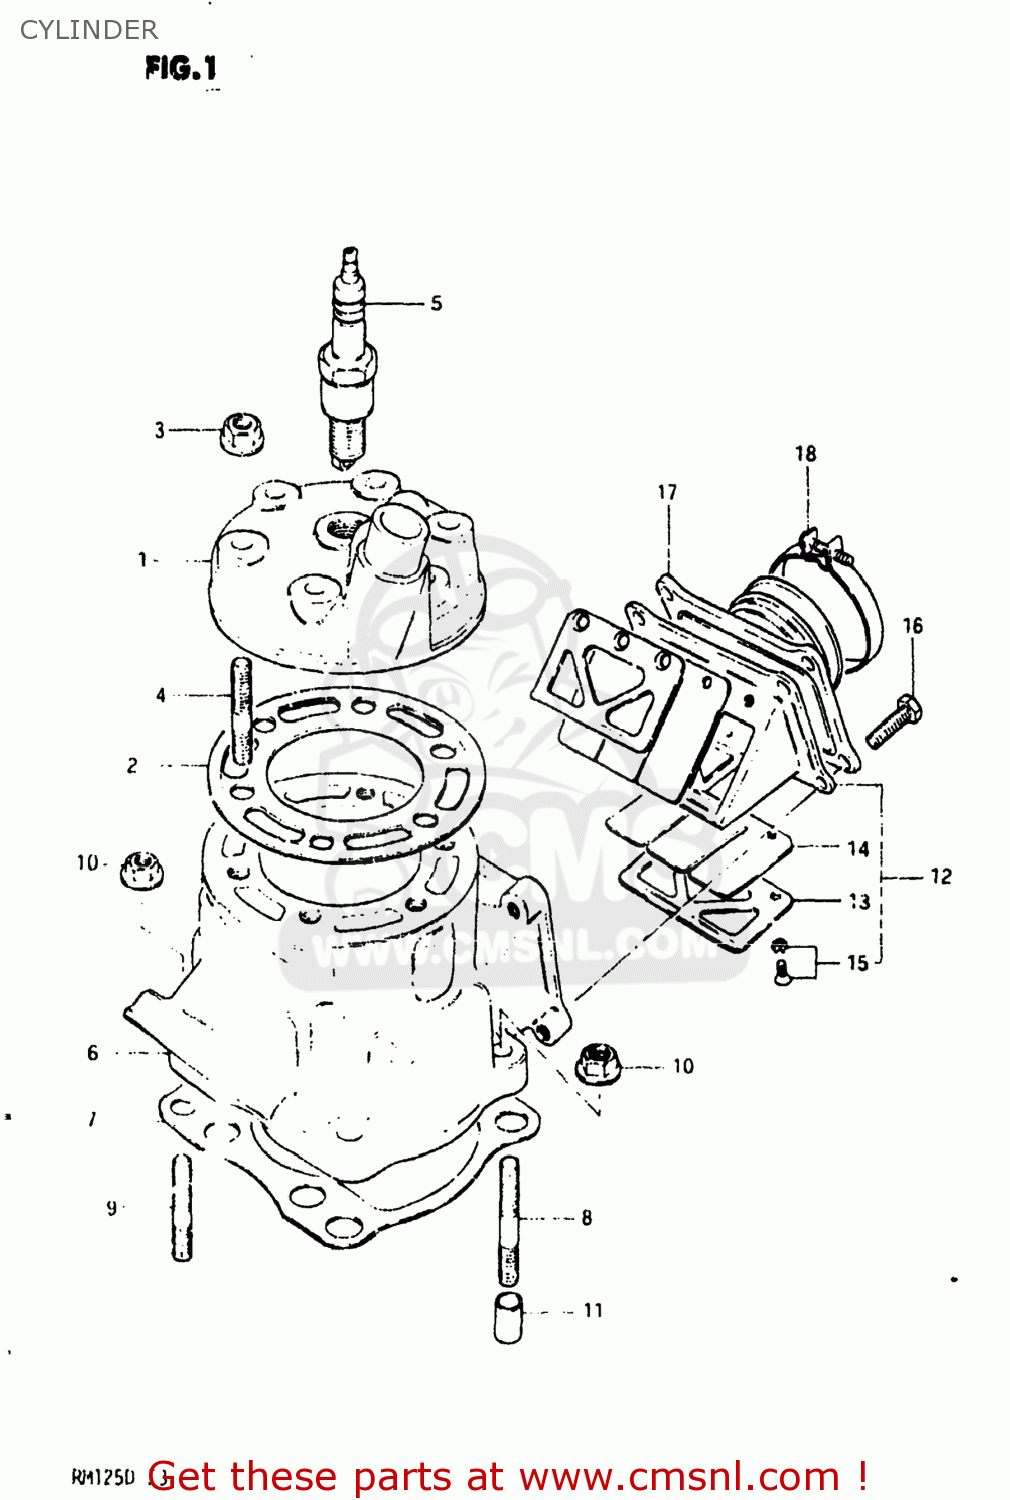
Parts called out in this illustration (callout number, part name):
1	HEAD,CYLINDER.
2	GASKET,CYLINDER HEAD (MCA)
3	NUT 8MM
4	STUD
5	SPARK PLUG
6	CYLINDER
7	GASKET,CYLINDER (MCA)
8	STUD
9	STUD
10	NUT 8MM
11	PIN
12	VALVE ASSEMBLY,REED
13	STOPPER,REED VALVE
14	VALVE,REED
15	SCREW
16	BOLT
17	PIPE,INTAKE
18	CLAMP
